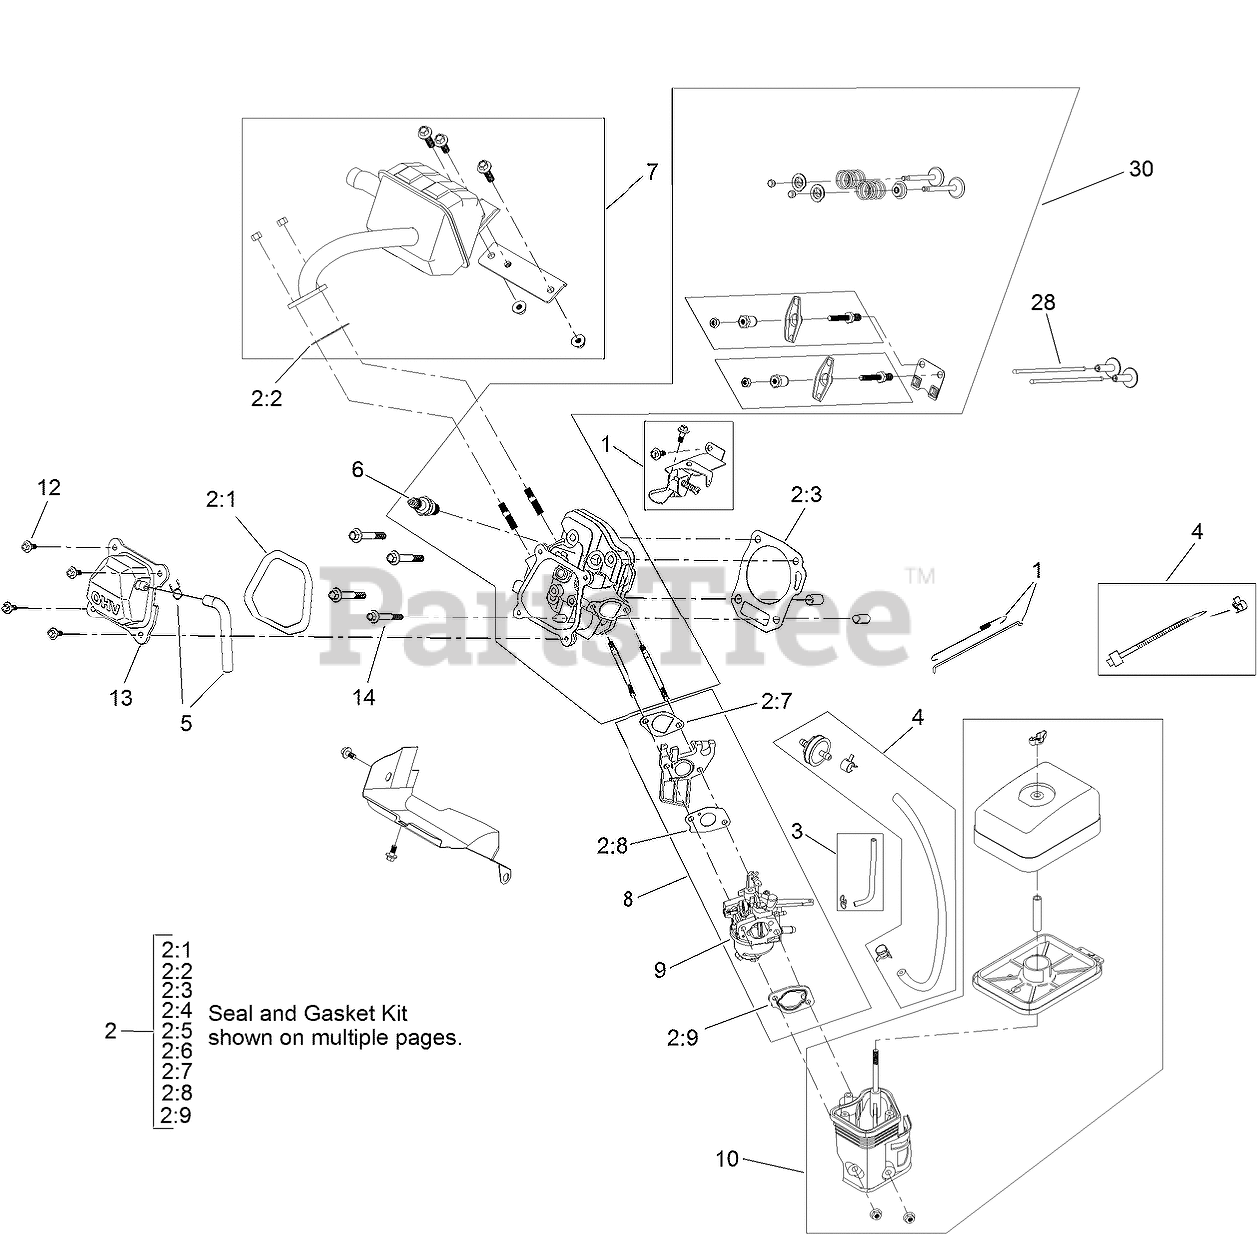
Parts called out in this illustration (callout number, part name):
1	GOVERNOR KIT
2	GASKET AND SEAL KIT
2:1	GASKET-COVER, VALVE
2:2	GASKET-EXHAUST
2:3	GASKET-HEAD, CYLINDER
2:4	SEAL-OIL
2:5	SEAL-OIL
2:6	GASKET-COVER, CRANKCASE
2:7	GASKET-CARBURETOR
2:8	GASKET-CARBURETOR
2:9	GASKET-CARBURETOR
3	PRIMER LINE KIT
4	FUEL LINE KIT
5	BREATHER TUBE KIT
6	PLUG-SPARK
7	MUFFLER KIT
8	CARBURETOR KIT
9	CARB REPAIR KIT WITH GASKETS
10	HEATER BOX KIT
12	SCREW-HHF
13	VALVE COVER ASM
14	SCREW-HHF
28	ROD-PUSH
30	COMPLETE HEAD ASM
